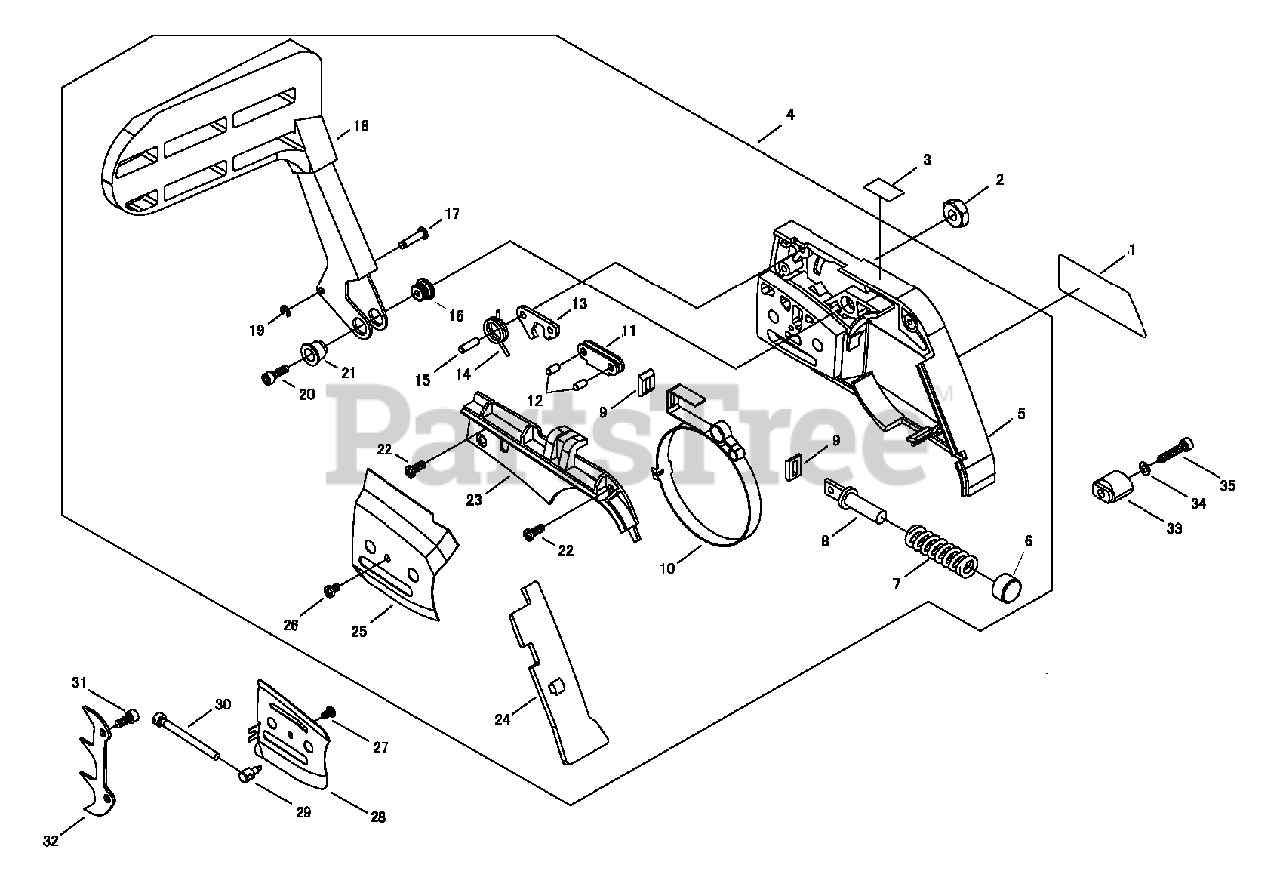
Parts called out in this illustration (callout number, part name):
1	LABEL - TRADE
2	NUT - 8
3	LABEL - CAUTION
4	CHAIN BRAKE ASSY
5	GUARD, SPROCKET
6	STOPPER
7	SPRING, BRAKE
8	HOLDER, SPRING
9	ADJUST PLATE
10	BAND, BRAKE
11	TIE, CABLE
12	PIN - LOCATING
13	LEVER - INNER
14	SPRING, LEVER
15	PIN - LOCATING
18	LEVER, BRAKE
19	RING, RETAINING
20	SCREW - 4X12
22	SCREW - 4X12 -- TAPPING
23	COVER, BRAKE
24	PROTECTOR
25	GUIDE PLATE D
26	SCREW - 4X8 -- TAPPING
27	SCREW - 4X7
28	GUIDE PLATE C
29	TENSIONER, CHAIN
30	SCREW, TENSIONER
33	CATCHER, CHAIN
